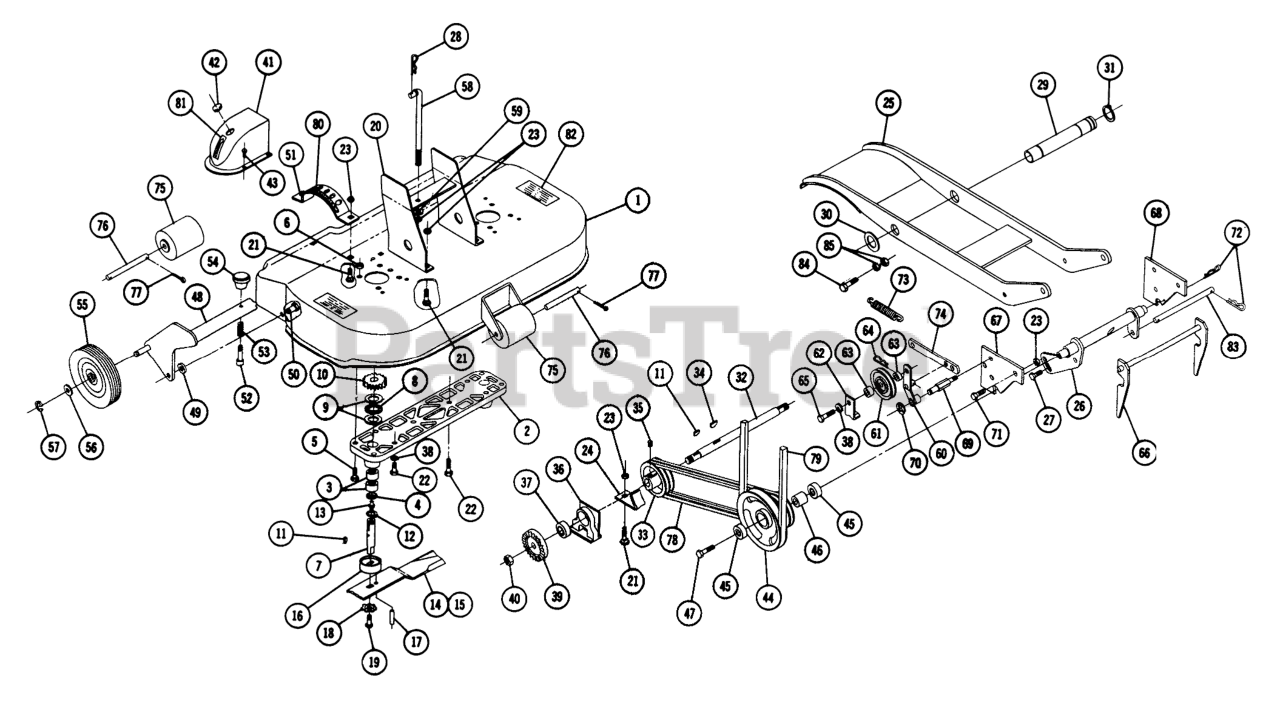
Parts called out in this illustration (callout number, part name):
1	Ass-y Deck
2	Housing
3	NEEDLE BEARING
4	Seal
5	Bolt 5/16-18 x 11/4
6	Nut 5/16-18
7	Spindle
8	Bearing Thrust
9	WASHER-THRUST
10	SPUR GEAR
11	WOODRUFF KEY
12	RING-SNAP, EXTERNAL
13	Zerk
14	Blade R.H. 18"
15	Blade L.H. 18"
16	SPINDLE CUP
17	SPIROL ROLL PIN
18	WASHER
19	Bolt 3/8-16 x 7/8
20	Ass-y Bracket-Hanger
21	Bolt-3/8-16 x 3/4
22	Bolt 3/8-16 x 1
23	3/8-16 E.S.
24	Guard
25	Ass-y-Drag Link
26	ASSY HITCH SHAFT R
27	Bolt Whizlock 3/8-16 x 5/8
28	Hairpin
29	PIVOT TUBE
30	Washer
31	SNAP RING
32	SHAFT
33	PULLEY
34	Key
35	Set Screw
36	BEARING SUPPORT
37	Ball
38	Lockwasher
39	Gear
40	Nut 5/18 Elastic Stop
41	COVER GEAR
42	PLUG BUTTON
43	SCREW
44	Pulley 3 Groove
45	BALL BEARING
46	Spacer
47	Bolt Hex 7/16-14 x 3
48	Ass-y Support-Wheel
49	WASHER
50	Bolt-Special
51	QUADRANT R
52	PLUNGER
53	Spring
54	KNOB
55	WHEEL ASSY
56	SHIM-WASHER
57	E Ring
58	LIFT ROD R
59	Washer
60	Ass-y Idler Arm
61	Pulley
62	BRACKET GUARD
63	BUSHING
64	Hairpin
65	Bolt 3/8-16 x 1
66	Ass-y Latch & Shaft
67	PLATE R H
68	PLATE-MTG BRKT LH R (NS)
69	Support Idler
70	E Ring
71	Bolt 3/8-16 x 1
72	Hairpin
73	Spring
74	Link
75	Roller
76	Shaft
77	Cotter Pin
78	V-BELTS - MATCHED PR
79	V BELT
80	Decal-Height Control
81	Decal
82	Decal
83	Pin-Hitch
84	Bolt, 3/8-16 x 1/2
